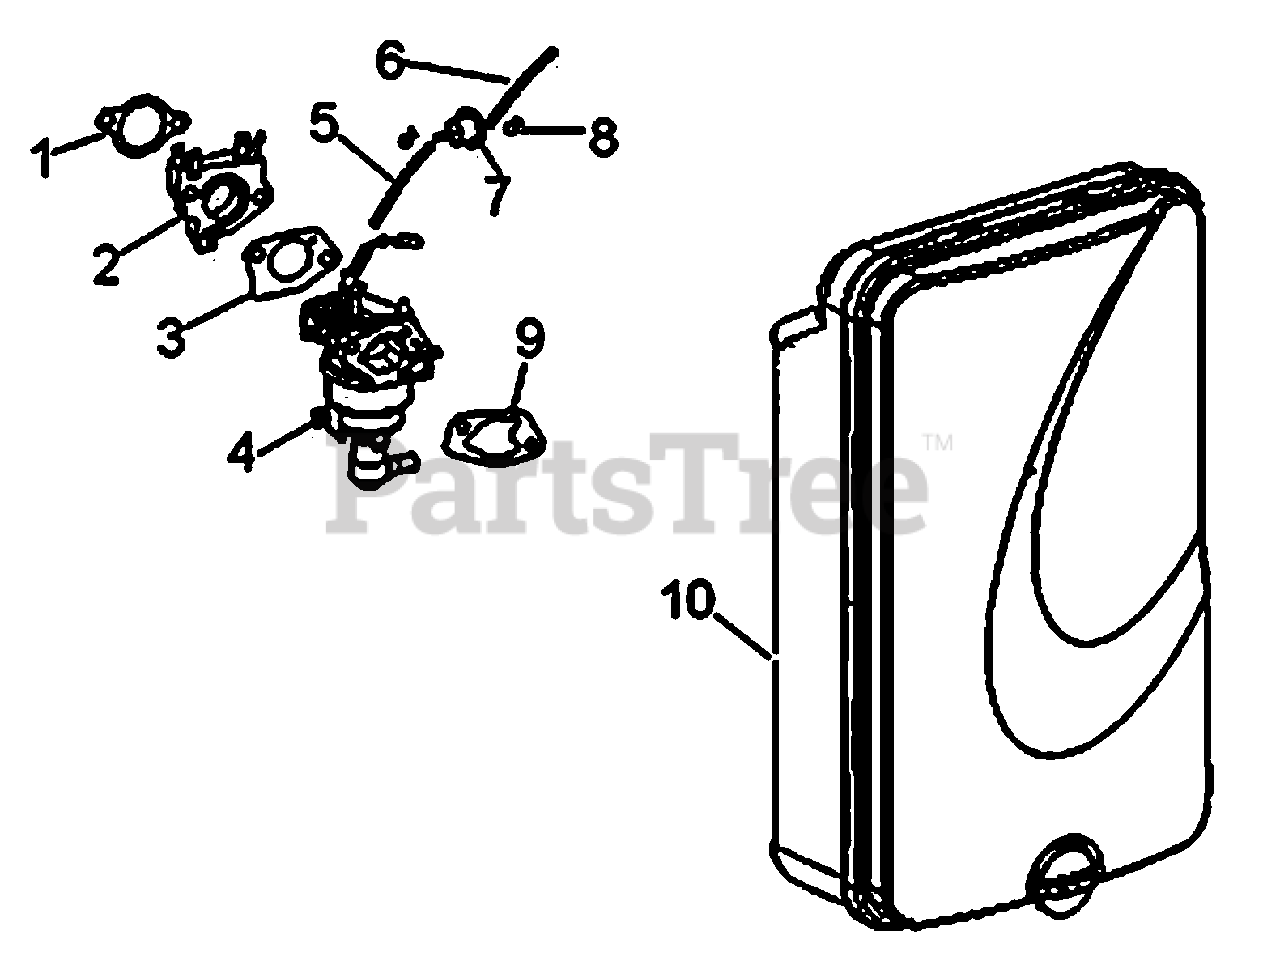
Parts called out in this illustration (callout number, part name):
1	GASKET, CARBURETOR
2	SPACER, CARBURETOR
3	GASKET, CARBURETOR
4	CARBURETOR ASSY.
5	TUBE, FUEL
6	TUBE, FUEL
9	GASKET, CARBURETOR
10	AIR CLEANER
